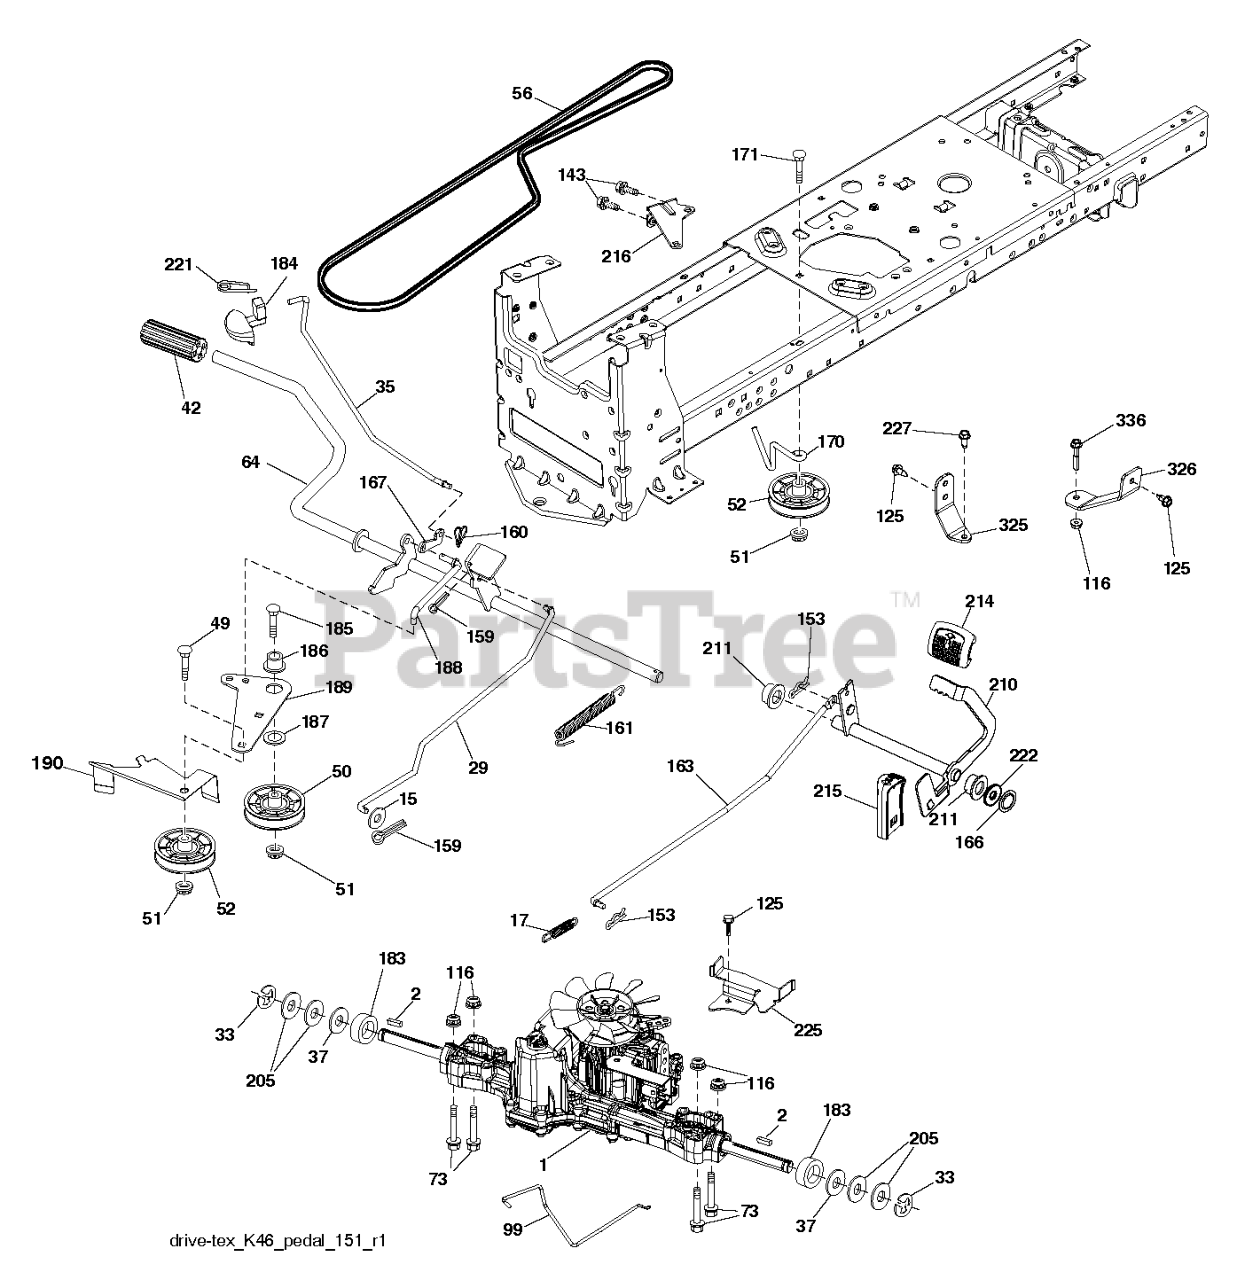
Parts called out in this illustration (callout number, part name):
2	Key, Square 2.5 x .1845/.1865 (AYP part number)
15	Washer 13/32 x 1-3/16 x 12 Gauge (AYP part number)
17	SPRING.BRAKE.K46.GREEN
29	ROD.BRAKE.K46
33	E-ring #5133-75 (AYP part number)
35	ROD ROD.PARKINGBRAKE.GT.HUSQ/P
37	WASHER.HARDENED
42	Cover Pedal Blk Round (AYP part number)
49	Bolt, Carriage 3/8-16 x 1-3/4 Grade 5 (AYP part number)
50	IDLER.FLAT.910.OFFSET
51	NUT LOCK FLG 3/8-16 UNC
52	IDLER.V-GROOVE.910.OFFSET
56	V-Belt Mower 42" 92 40 (AYP part number)
64	SHAFT.ASM.PEDAL.BRK.CNTR
99	ROD.SPRING.BYPASS.K46.LT.Z
116	NUT LOCK HEX FLANGE 5/16-18
125	SCREW
143	SCR 5/16-18 X 1/2 SELFTAP ZN
153	Spring Retainer 1" Zinc/cad (AYP part number)
159	Pin Cotter 1/8 x 3/4 CAD. (AYP part number)
160	RETAINER CLIP
161	X Spring Return Clutch 6 75 (AYP part number)
163	ROD.CONTROL.K57R.K46
166	NUT.PUSH.625
167	LATCH.BRAKE.SPRING
170	KEEPER.V-IDLER.CENTER.
171	Bolt, Carr. 3/8-16 x 1-3/4 Gr. 5 (AYP part number)
183	SPACER AXLE
184	HANDLE.PARKING.BRAKE.H (BLK)
185	Bolt, Carriage 3/8 - 16 x 2-3/4 (AYP part number)
186	SPACER.RETAINER
187	Washer 12/32 x 2 x 10 Gauge (AYP part number)
188	LINK.CLUTCH.GROUND DRIVE.LONG
189	BELLCRANK.GROUND.DRIVE.TEX.
190	KEEPER.BELLCRANK.DRIVE
205	Washer 25/32 x 1-5/8 x 16 Gauge (AYP part number)
210	ROCKER.ASM.PEDAL.CONTR
211	Bearing Nylon Blk 629 Id (AYP part number)
214	PEDAL.FORWARD.PAD.TEX
215	PEDAL.REVERSE.TEX.GT.4
216	BRACKET.PULLEY.IDLER.W/TEX
221	RETAINER.SPRING.CLIP.H
222	WASHER 21/32 X 1-1/4 X 10 GA.
225	KEEPER.BELT.TRANSAXLE.K46
227	Screw, Hex Washer Head, Threaded, Rolling 5/16-18 x 3/4 Type TT
325	BRACKET.TRQ.STP.46.20".TIRE.LH
326	BRCKT.PNT.TRQ.STP.46.20TIRE.RH
336	BOLT.5/16-18X1-3/4.FLANGED.HEX
